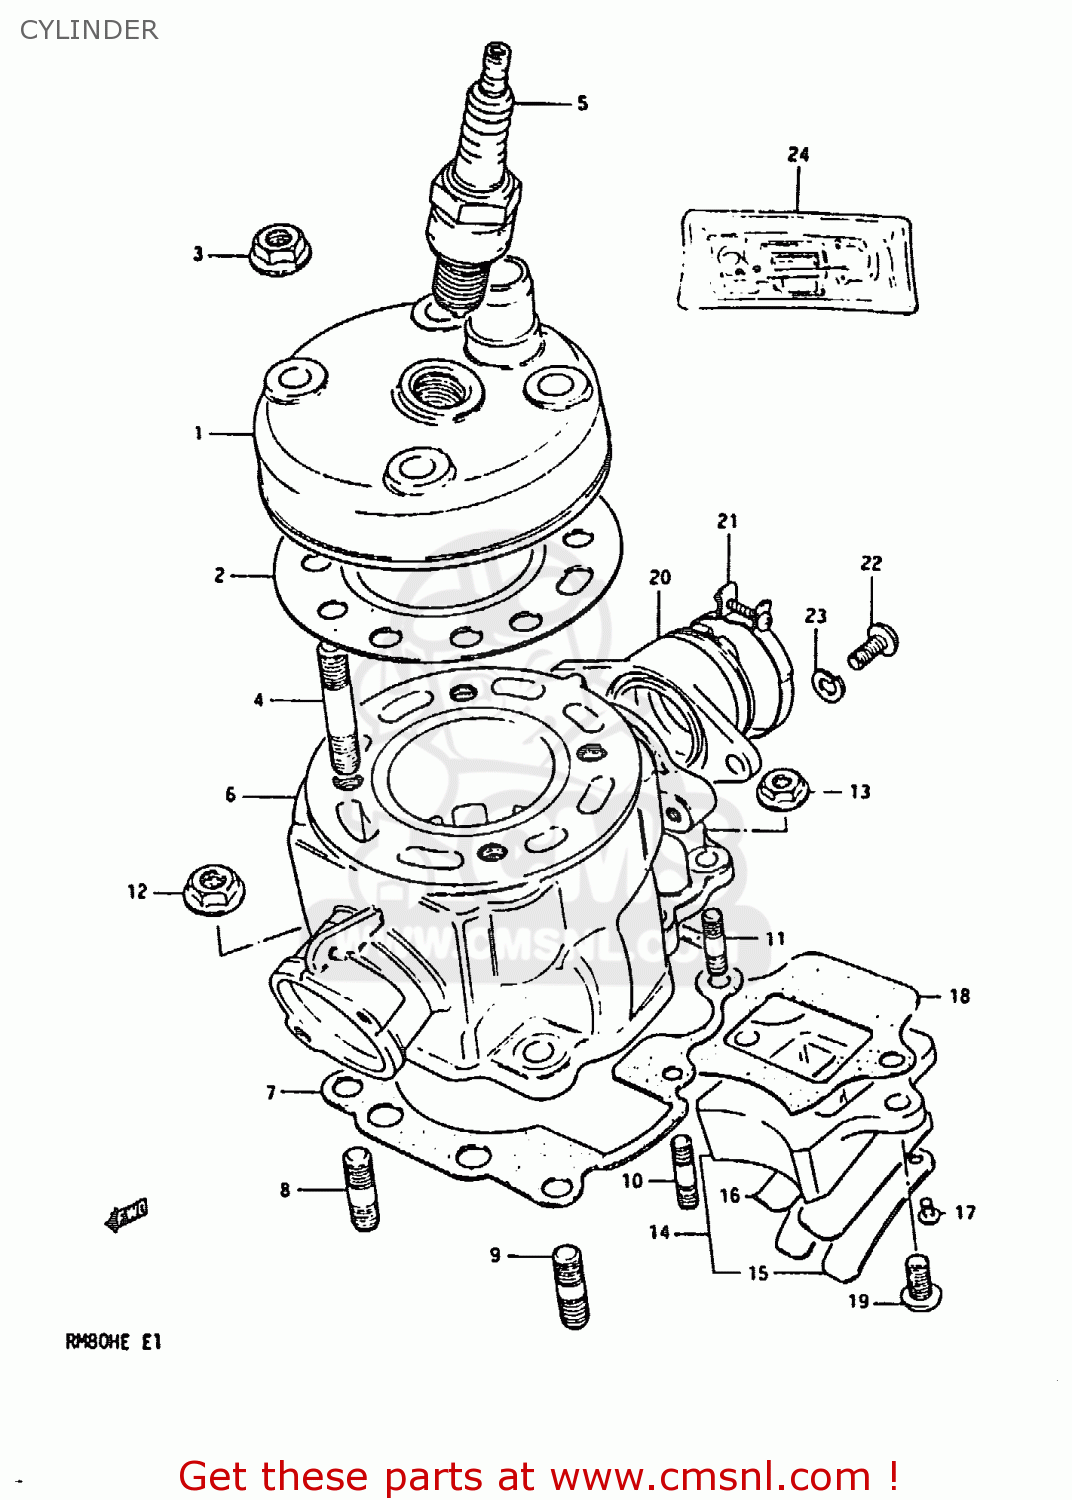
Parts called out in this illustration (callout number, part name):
1	HEAD,CYLINDER
2	GASKET,CYLINDER HEAD
3	NUT 8MM
4	BOLT,STUD
5	SPARK PLUG
6	CYLINDER
7	GASKET,CYLINDER (MCA)
8	BOLT,STUD(8X20)
9	STUD BOLT
10	STUD BOLT L:20
11	STUD 6X16
12	NUT 8MM
13	NUT
14	VALVE ASSY,REED
15	STOPPER,REED VALVE
16	VALVE,REED
17	SCREW,REED VALVE
18	GASKET,REED VALVE (MCA)
19	SCREW
20	PIPE,INTAKE
21	CLAMP
22	BOLT
23	LOCK WASHER
24	GASKET SET (MCA)
